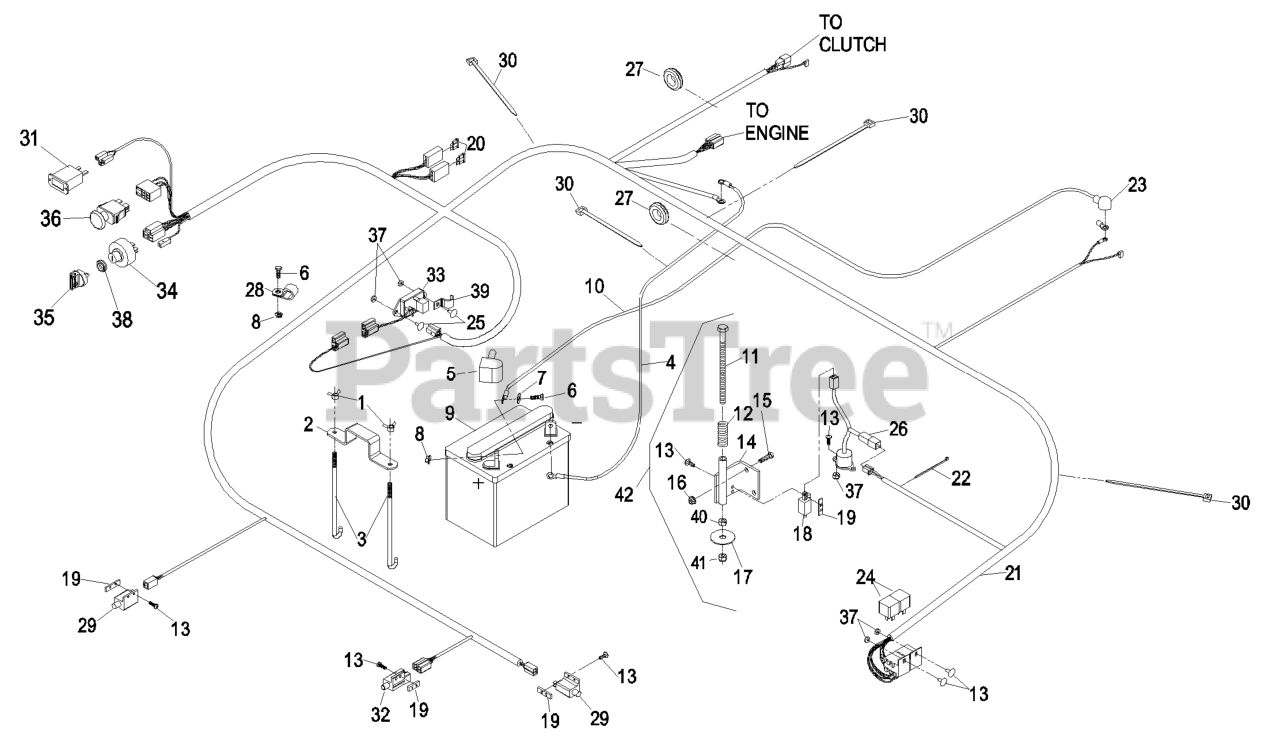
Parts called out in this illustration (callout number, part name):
1	WINGNUT
2	STRAP-HOLDDOWN
3	BOLT-HOLDDOWN
4	WIRE-GROUND
6	SCREW-HH
7	WASHER-FLAT
11	SCREW-HH
12	SPRING-SWITCH, SEAT
13	SCREW-PPH
14	BRACKET-SWITCH, SEAT
15	SCREW-HH
18	SWITCH-CLOSED, NORMALLY
19	PLATE-TAPPED
20	FUSE-BLADE TYPE, 20 AMP
21	HARNESS,WIRE LCT KC
22	TIE-CABLE
23	INSULATOR-SOLENOID
25	SCREW-HEAD, TRUSS
27	GROMMET
28	CLIP-LOOM
29	SWITCH-OPEN, NORMALLY
30	TIE-PLASTIC
31	METER-HOUR
33	MODULE-DELAY, SEAT
35	KEY-IGNITION
37	NUT-LOCK, NI
38	NUT-SWITCH, IGNITION
39	CLIP-HALF, LOOM
40	NUT-HEX
41	NUT-LOCK, NI
42	ASM,SEAT SWITCH ACTUATOR
